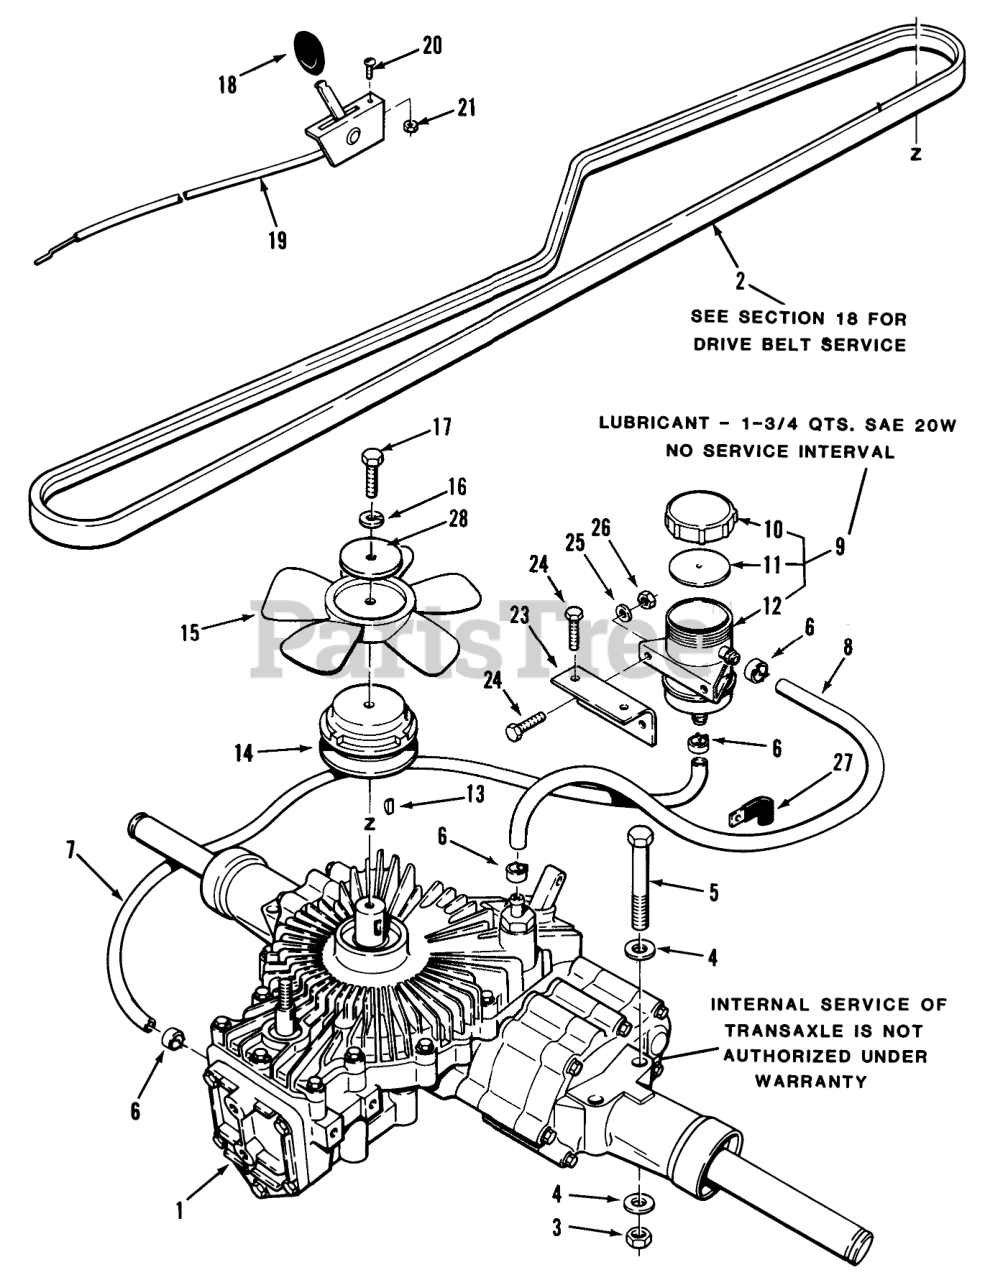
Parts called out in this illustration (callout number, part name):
1	Hydrostatic Transaxle (Eaton Model 750-012)
2	BELT V
3	Nut
4	WASHER 5/16 SAE
5	Pin-Cotter
6	CLAMP
7	S/A 9" OF 114702
8	S/A 27" OF 114702
9	Hydro Reservoir Complete (includes items 10, 11 & 12)
10	Cover
11	COVER GASKET
12	RESERVOIR
13	HARD HI PRO KEY
14	PULLEY-HYDRO
15	BLADE-FAN
16	Washer
17	Bolt
18	KNOB-THROTTLE
19	CABLE-PUSH VALVE
20	Screw #10-24 x 1/2
21	Nut
23	BRKT-RESERVOIR MT R
24	Bolt
26	Nut
27	CLIP
28	WASHER
